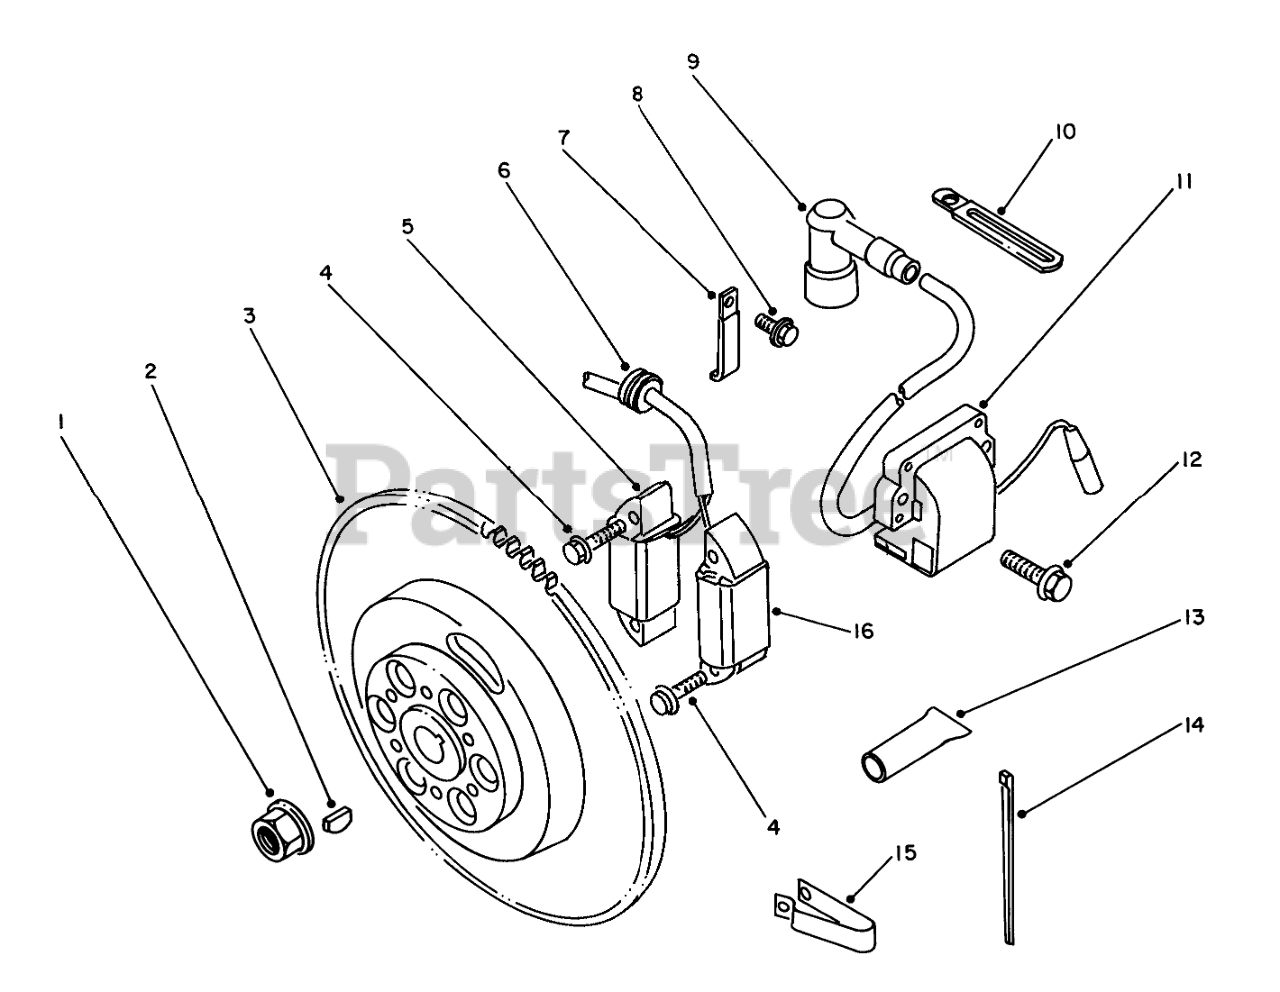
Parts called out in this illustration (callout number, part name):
1	Nut
3	Rotor
5	Coil-Exciter
6	Grommet
7	Clamp
9	SPARK PLUG CAP
10	Clamp
11	IGNITER UNIT
13	Cap-Connector
14	Clamp
15	Clamp
16	Coil-Magneto Primary
